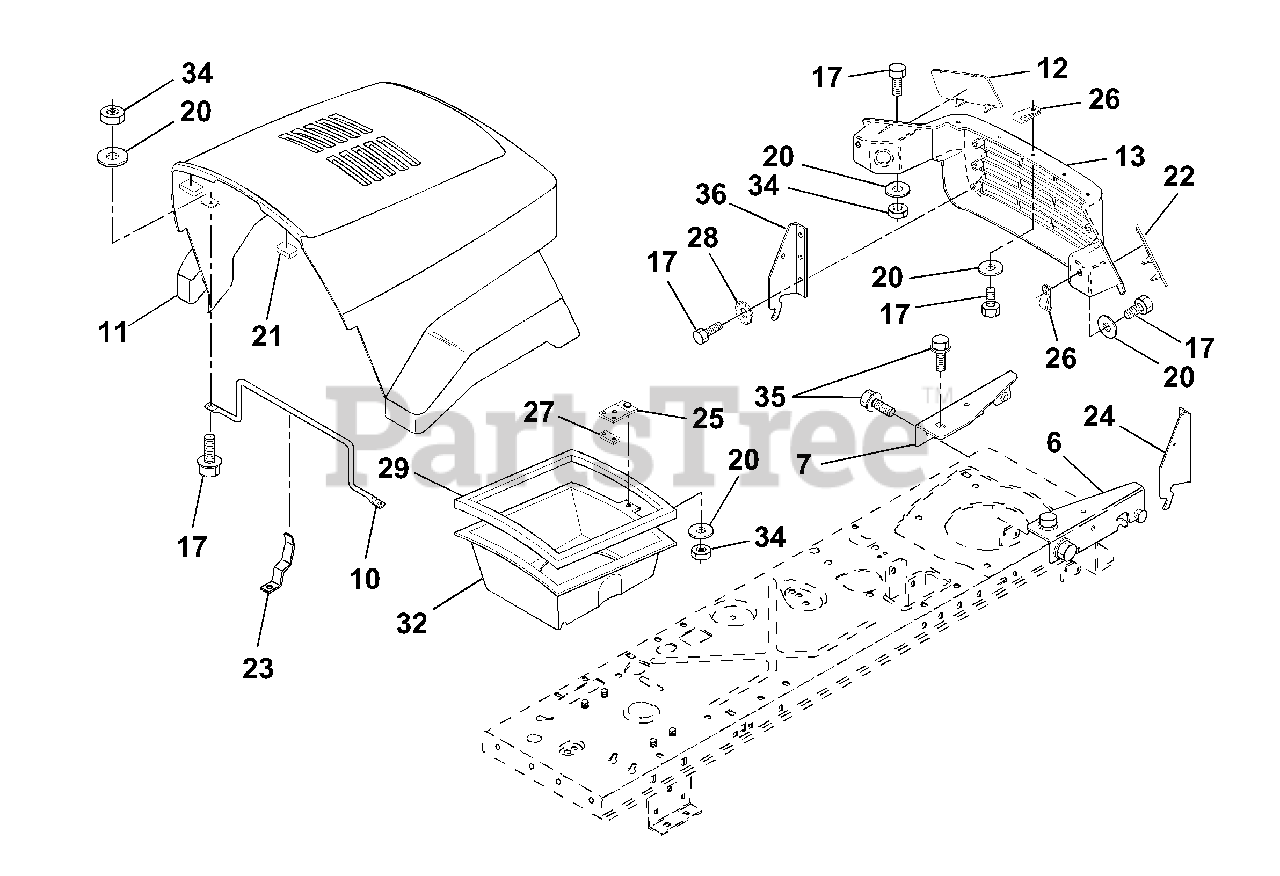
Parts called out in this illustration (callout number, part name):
6	Bracket Asm. Pivot Hood RH
7	Bracket Asm. Pivot Hood LH
10	Brace Hood
13	Grille
17	Bolt Fin Hex 1/4-20 x 5/8
20	Washer, Flat 1/4
21	Bumper Hood
23	Latch Hood
24	Bracket Pivot Hood RH
25	Clip Asm. Duct Air
26	Clip Tinnerman
27	Clip Tinnerman
28	Washer Lock Ext. Tooth
29	Strip Foam
32	Duct Air Hood
34	Nut Crownlock 1/4-20 Unc
35	Screw Thdrol 5/16-28 x 3/4
36	Bracket Pivot Hood LH
